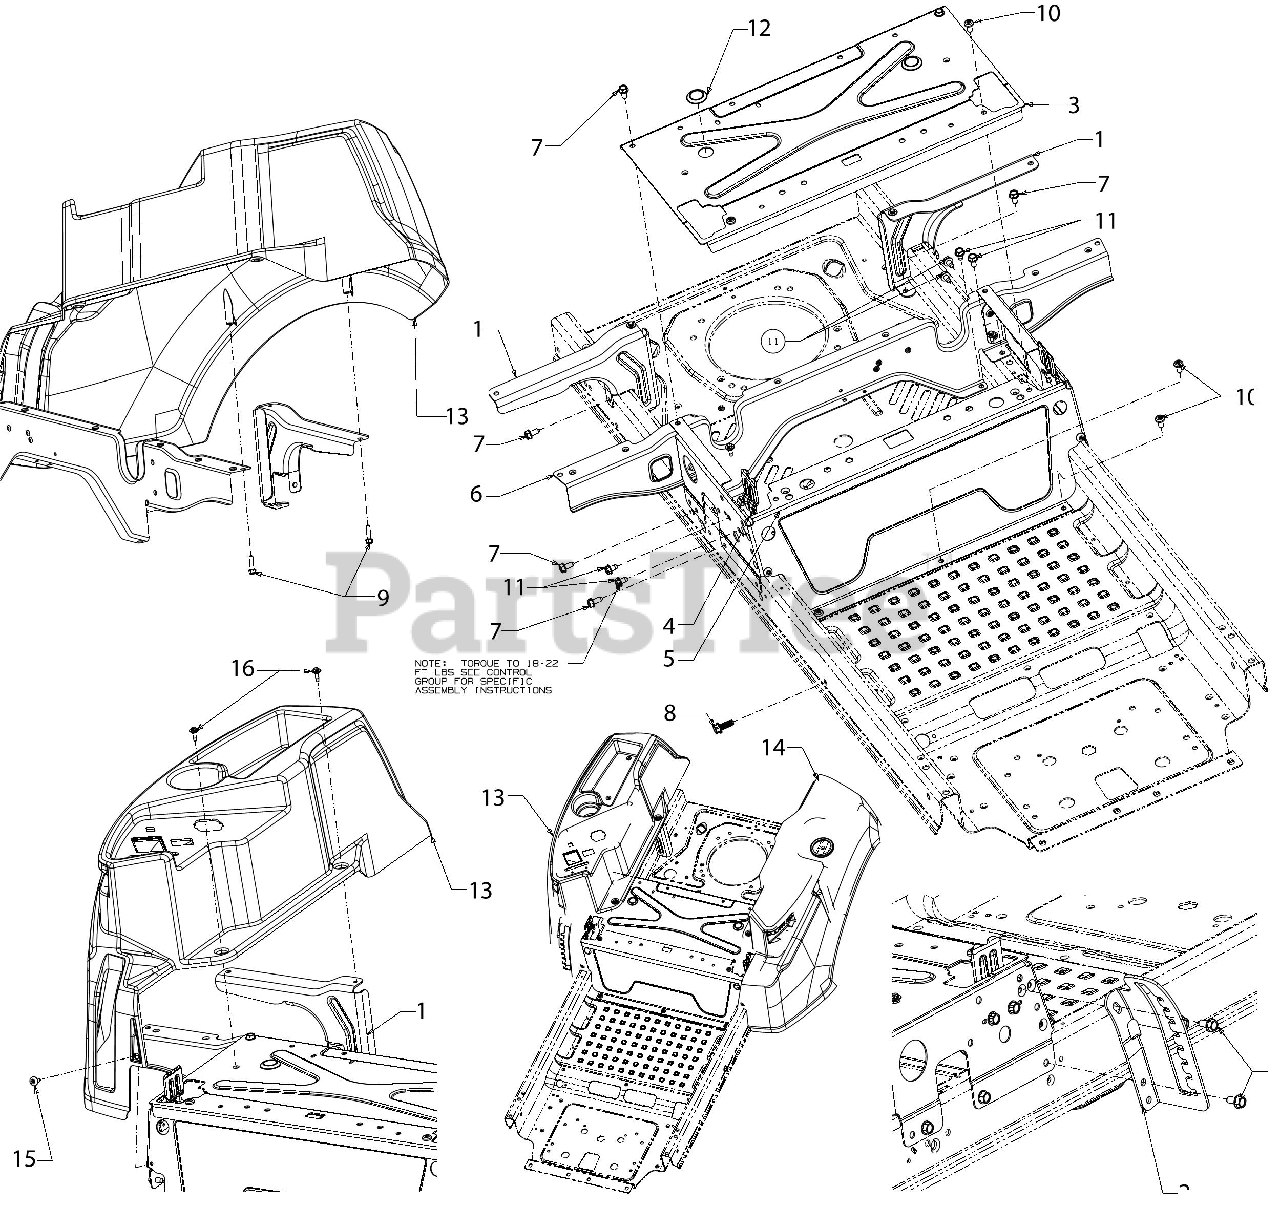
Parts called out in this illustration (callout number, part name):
2	HEIGHT INDEX BRACKET
7	SCREW 5/16-18 x .750
8	SCREW 3/8-16 x 1
9	SCREW 5/16-14 x 1
10	SCREW 5/16-18 x .750
11	SCREW 5/16-18 x .500
13	CONSOLE (RH)
14	CONSOLE (LH)
15	SHOULDER SCREW M6-1 .368 X.115
16	SHOULDER SCREW M6-1 .368 X.115
